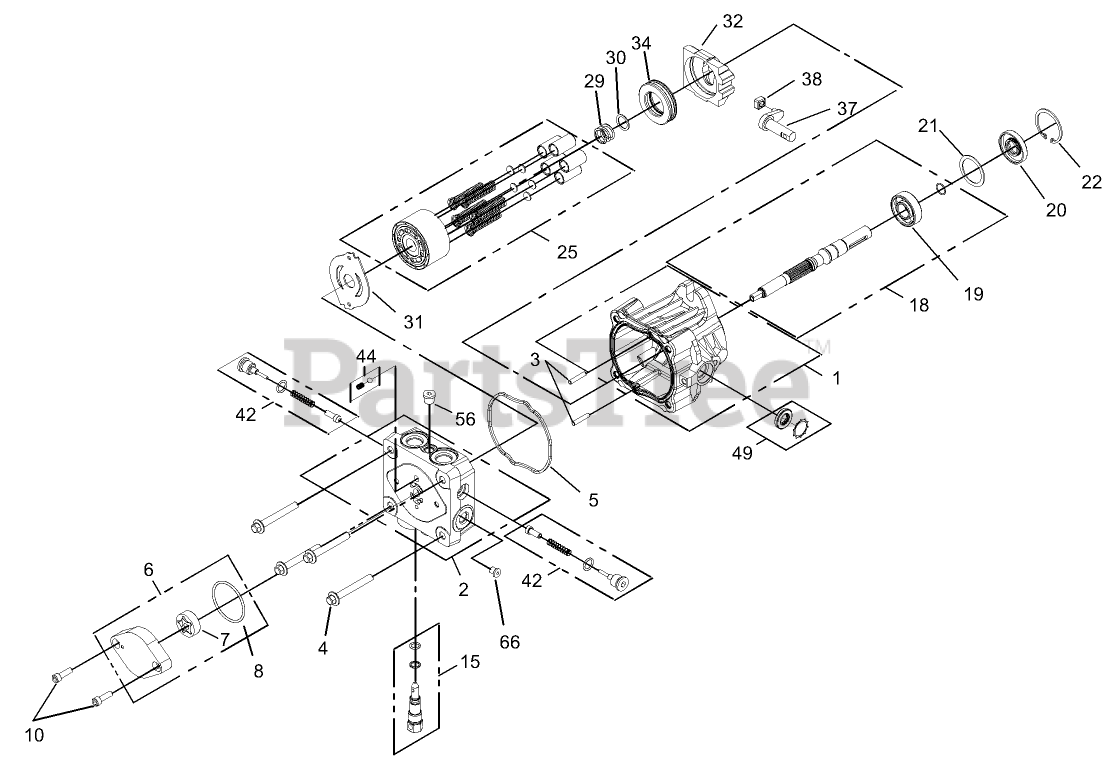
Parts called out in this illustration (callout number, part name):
1	HOUSING KIT
2	END CAP KIT (W/POPPETS)
3	PIN-HEADLESS, STRAIGHT
4	BOLT-HF
5	O-RING
6	CHARGE PUMP KIT
7	GEROTOR ASM
8	O-RING
10	SCREW-HSH
15	BYPASS VALVE KIT
18	INPUT SHAFT KIT
19	BEARING-BALL
20	SEAL-LIP
21	SPACER
22	RING-RETAINING
25	CYLINDER BLOCK ASM
29	SPRING-BLOCK
30	WASHER-THRUST
31	Plate-Valve
32	SWASHPLATE-VARIABLE
34	BEARING-THRUST
37	ARM-TRUNION
38	GUIDE-SLOT
42	VALVE-CHECK (W/POPPET)
44	CHARGE RELIEF VALVE KIT
49	TRUNNION SEAL / RETAINER KIT
56	PLUG-HSH
66	PLUG-HSH
